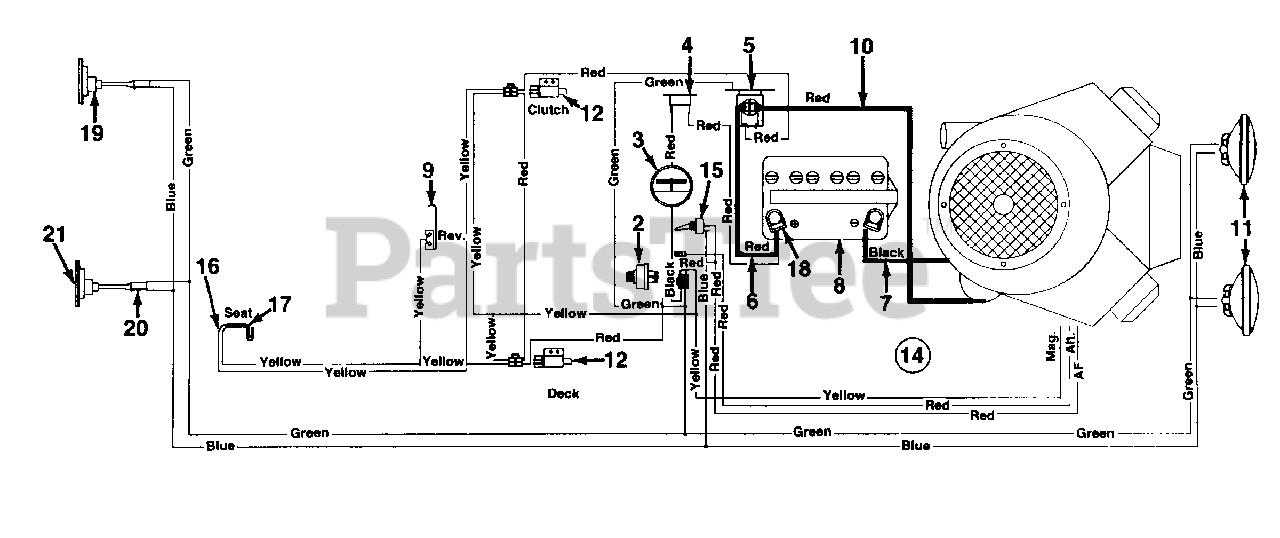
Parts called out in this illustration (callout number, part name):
2	Ignition Switch
3	Ammeter
4	Circuit Breaker 8 Amp
5	Solenoid
6	Electric Wire
7	Electric Wire
8	Battery
9	Spring Switch
10	Electric Wire
11	Headlights
12	Safety Switch
14	Wire Harness
15	Light Switch
16	Safety Switch
17	Safety Switch
18	Battery Boot
19	Taillight
20	Taillight Harness
21	Taillight Bulb
